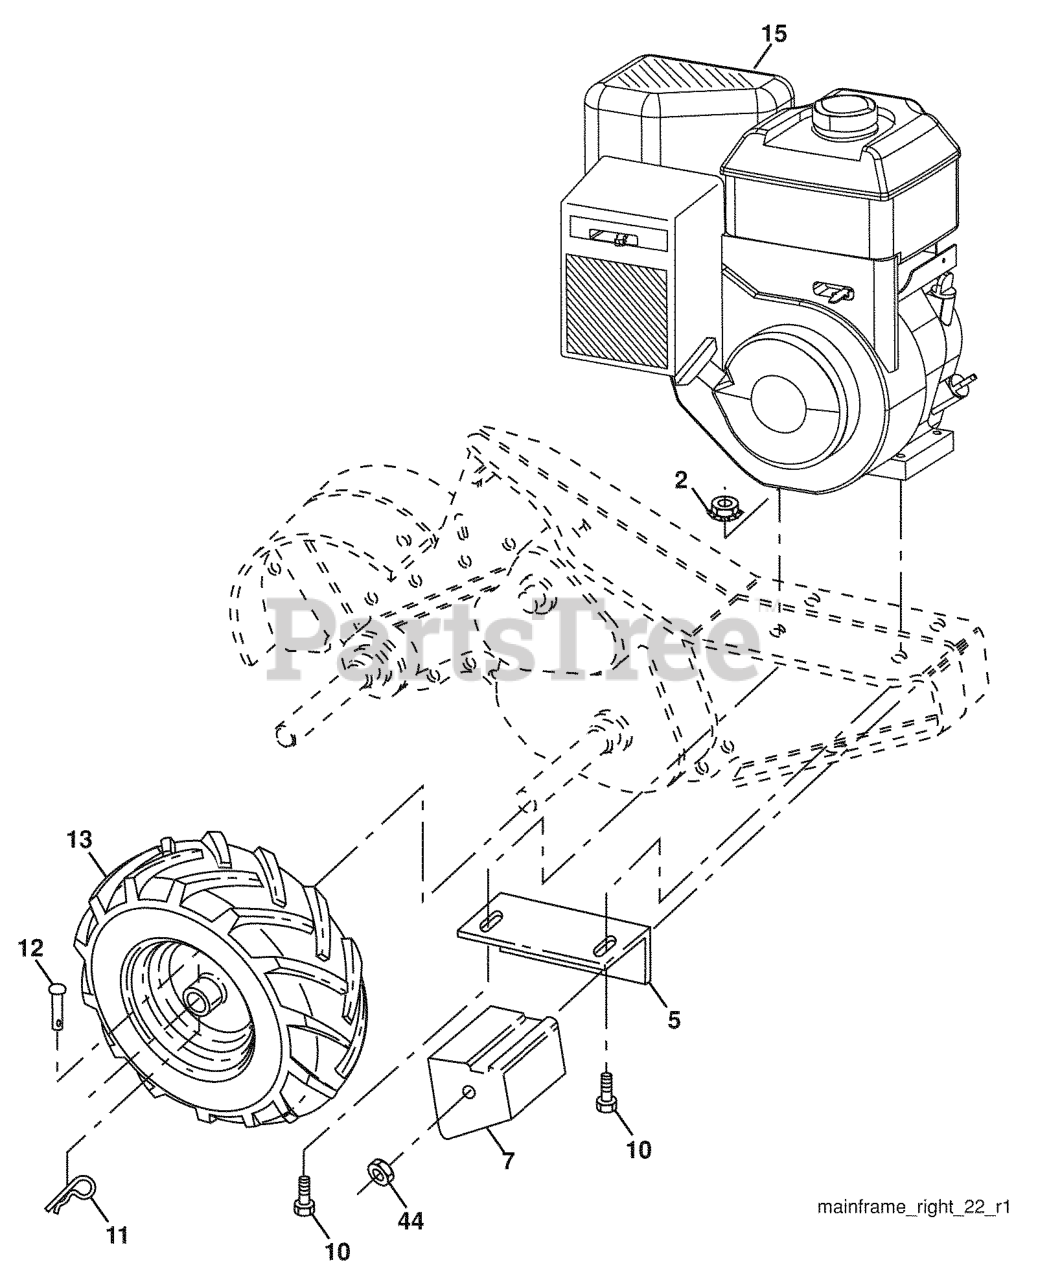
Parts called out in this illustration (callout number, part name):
2	LOCKNUT-FLANGE 5/16-18
5	DNO BRACKET RH CRT
7	COUNTERWEIGHT, RH
10	BOLT
11	RETAINER M
12	RIVET,DRILLED
13	TIRE.16X4-8.CHEVRON.TILLER
